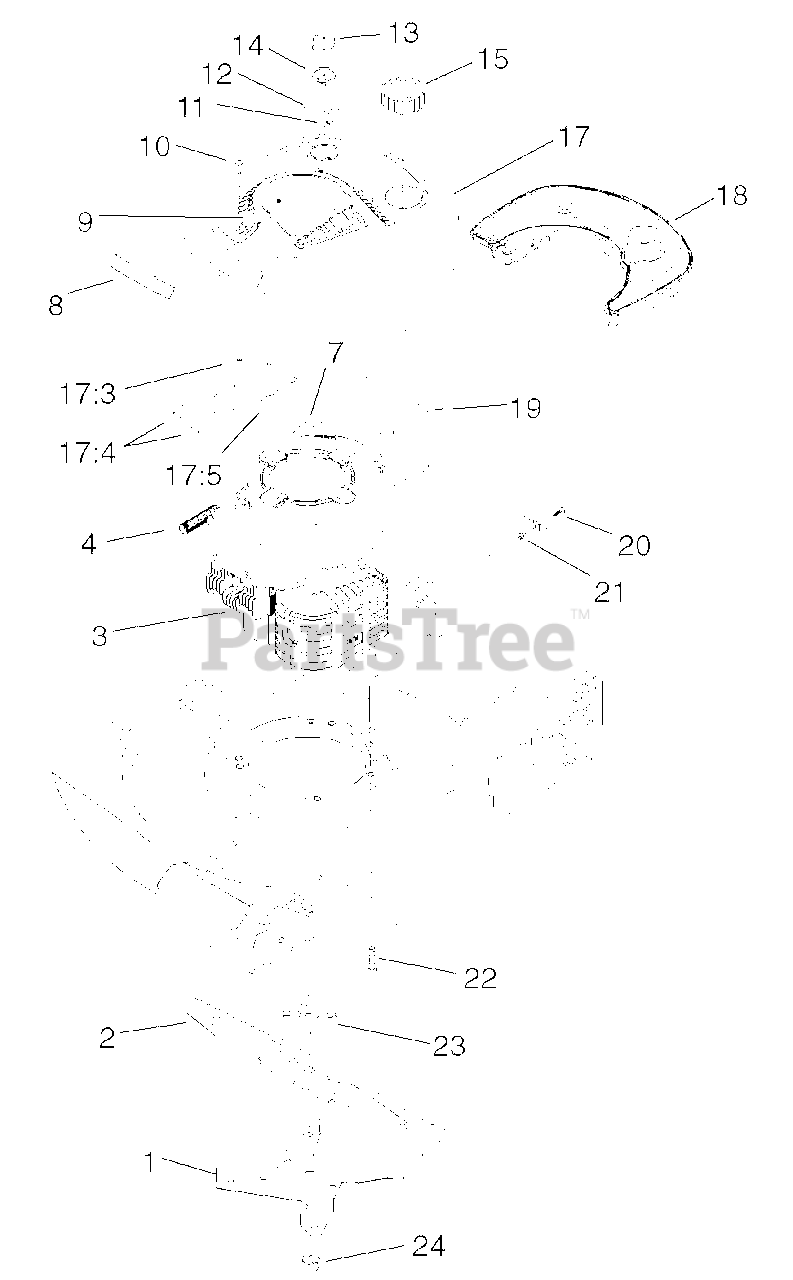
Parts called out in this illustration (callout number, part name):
1	FAN-MULCHING
2	BLADE-20.88 INCH
4	SPRING-COMPRESSION
7	LINE-FUEL
8	APPLIQUE-SHROUD
9	DECAL-RECOIL
11	STOP-ROPE
13	BULB-PRIMER
14	BODY-PRIMER
15	FUEL AND OIL CAP ASM
17	SHROUD AND RECOIL COVER ASM
17:3	NUT-PUSH
17:4	STRIP-FOAM
17:5	STRIP-FOAM
19	PAD-FOAM
21	NUT-HEX
22	SCREW-HH, SEMS
23	PLATE AND COLLAR ASM
24	NUT-BLADE
